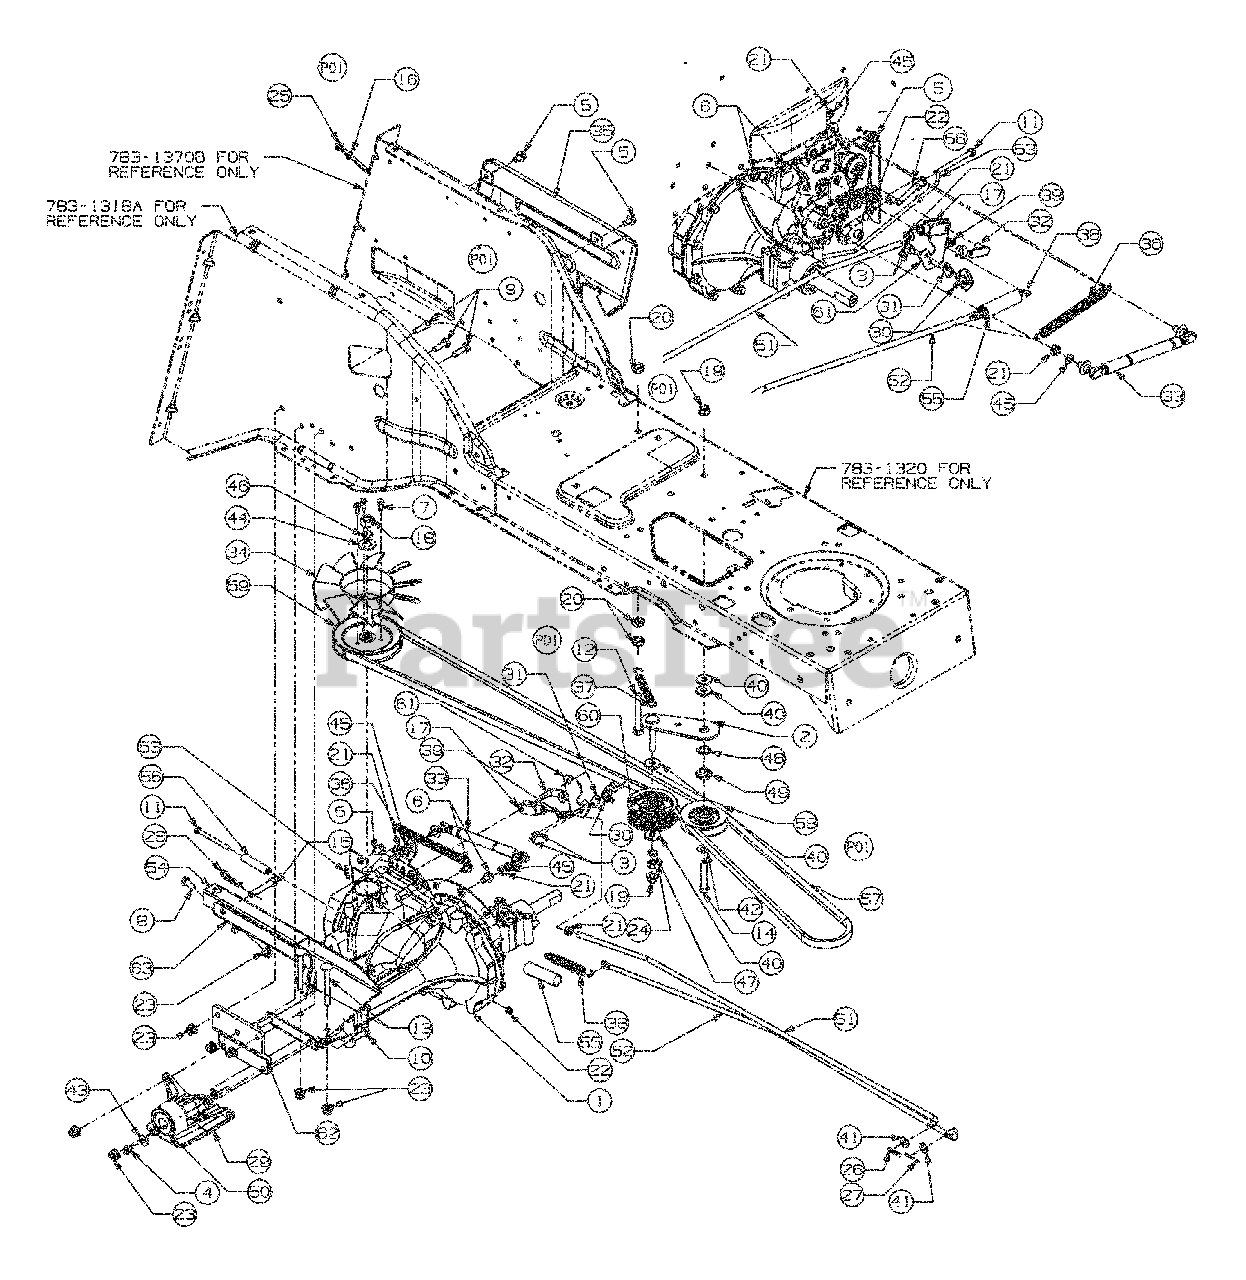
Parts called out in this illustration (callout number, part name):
1	TRANS ASM:HYDRO
2	BRKT ASM:IDLR:DBL
3	SCR:AB:#8-18:0.500:HXINDWSH
4	SCR:TT:1/4-20:0.500:HXINDWSH
5	SCR:TT:5/16-18:0.625:HXINDWSH
6	SCR:TT:5/16-18:0.500:HXINDWSH
7	SCR:C:#12-24:0.625:HXINDWSH
8	HHCS:M8-1.25:20.00:GR8.8:STD
9	HHCS:M8-1.25:25.00 LG DIN 933
10	HHCS:M8-1.25:30.00 LG DIN 933
11	HHCS:M6-1:70.00:DIN 931
12	BOLT:M10 X 70MM LG
13	SCR:CARR:M8-1.25:75 LG DIN 603
14	HHCS:3/8-16:2.00:GR5:STD
15	PIN:CLEVIS:3/8 DIA X 2.015
16	PIN:GDE:.250 DIA X 1.68 LG
17	FRL:M8-32 X 18 DIA DIN 71752
18	NUT:HEX:1/2-20:GR2
19	NUT:FLGLK:3/8-16:GRF:TOP LK
20	NUT:M10 X 1.25
21	NUT:HEX:M8-1.25 DIN 934
22	NUT:HEXLK:M6-1:NYLON DIN 985
23	NUT:FLGLK:M8-1.25 DIN 6926
24	NUT:HEX:3/8-16:GR8
25	NUT:1/4-20:HEXFLG:LOK:GRF
26	PIN:COT:.072 DIA. X 1.13 LG
27	PIN:COT:3/32:1.0
28	PIN:COT:.125 X 1.75 INTERNAL
29	SUPT:CSTG
30	SW:SPR:SHORT
31	PLATE: INSULATOR NUT
32	CLIP:M8-32 DIN 71752
33	CYL: DAMPER
34	FAN:BLADE:10
35	CVR:HYDRO
36	SPR:EXTN:.50 DIA X 6.37 LG
37	SPR:EXTN:.50 DIA X 3.97 LG
38	SPR:EXT:.59 OD X 4.00 LG
39	SPR:CMPRS:9.6 MM OD X 21.5 LG
40	WASH:FLAT:.385 X 1.0 X .135
41	WASH:FLAT:.344 X .688 X .065
42	WASH:FLAT:.406 X .875 X .059
43	WASH:FLAT:6.4 IDX18 OD DIN9021
44	WASH:FLAT:15 ID X 28 OD DIN125
45	WASH:SCHNORR:8MM
46	WASH:LOCK:SCHNORR 13 X 18 X1.7
47	WASH:LOCK:SCHNORR 10.5X16X1.6
48	WASH:FLAT:16 X 21 X 1 DIN 988
49	SPCR:SHLDR:1.00 X .38 X .38
50	BRG:BALL:.75ID X 40MM OD X12MM
51	ROD:CONT:HYDRO 500 LG
52	ROD:BRAKE:HYDRO 500 LONG
53	ROD:HYDRO:BYPASS 500 LWB
54	TUBE:SQ:30MM X 30MM X 216MM LG
55	SPCR:.640 ID X .76 OD X 2.63
56	SPCR:.275 ID X .50 OD X 2.28
57	BELT:V TYP:1/2 X 105 LG POLY
58	V-IDLER 6.06 OD-NH#VH-39-AB
59	PUL:TRANS:4.50 DIA.
60	FLAT IDLER WITH FLANGES 2.75
61	BRKT:ACTR:SW EURO
62	BRKT:MT:HYDRO
63	BRKT:HITCH:500
